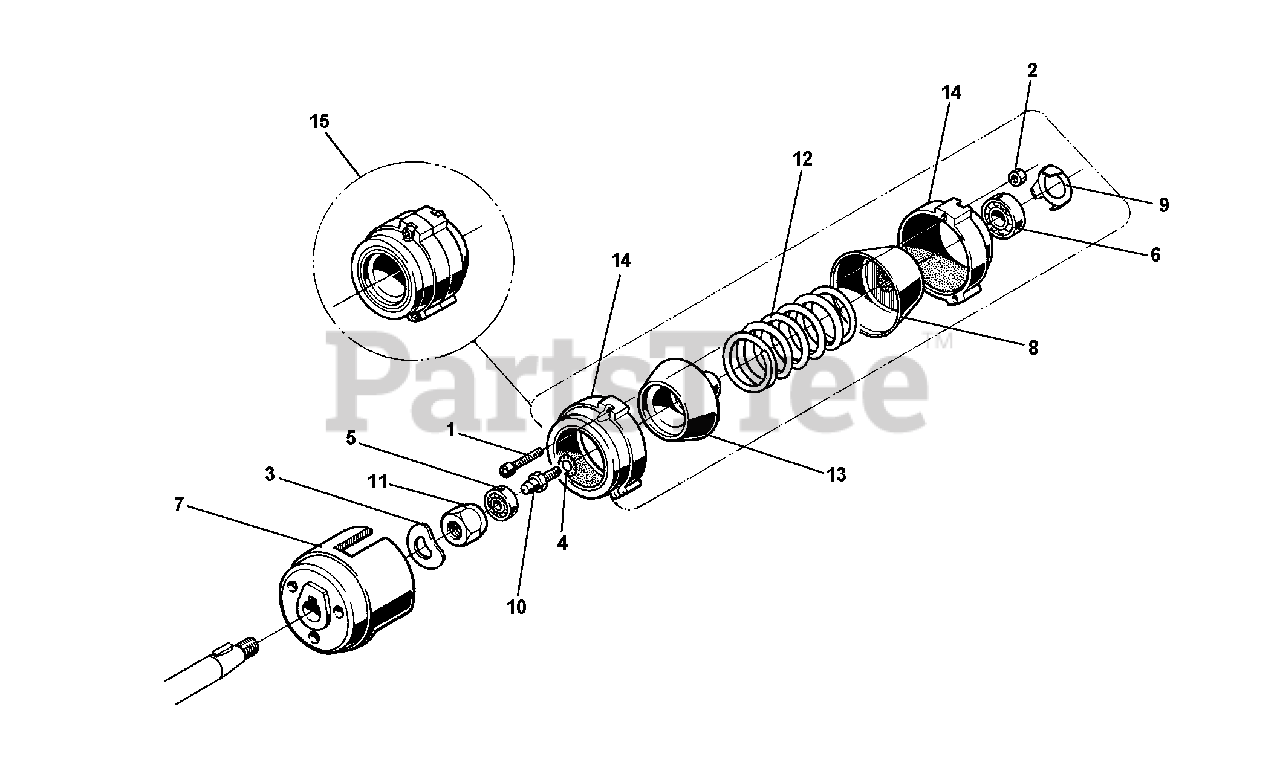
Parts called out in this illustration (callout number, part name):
1	SCREW TCCEI M6 X 30 UNI 5931
3	WASHER, LOCK 17
4	WASHER, LOCK AZ 8.4
5	BEARING 10 X 30 X 9 6200 2RS ST
6	BEARING SKF 17 X 40 X 12 6203 ST
7	CLUTCH BELL D 23.S
8	MOBILE CONE
9	BEARING PLATE
10	CENTERING SCREW M8
11	SPECIAL NUT
12	SPRING CLUTCH
14	CLUTCH RING
15	DOUBLE CONE CLUTCH
